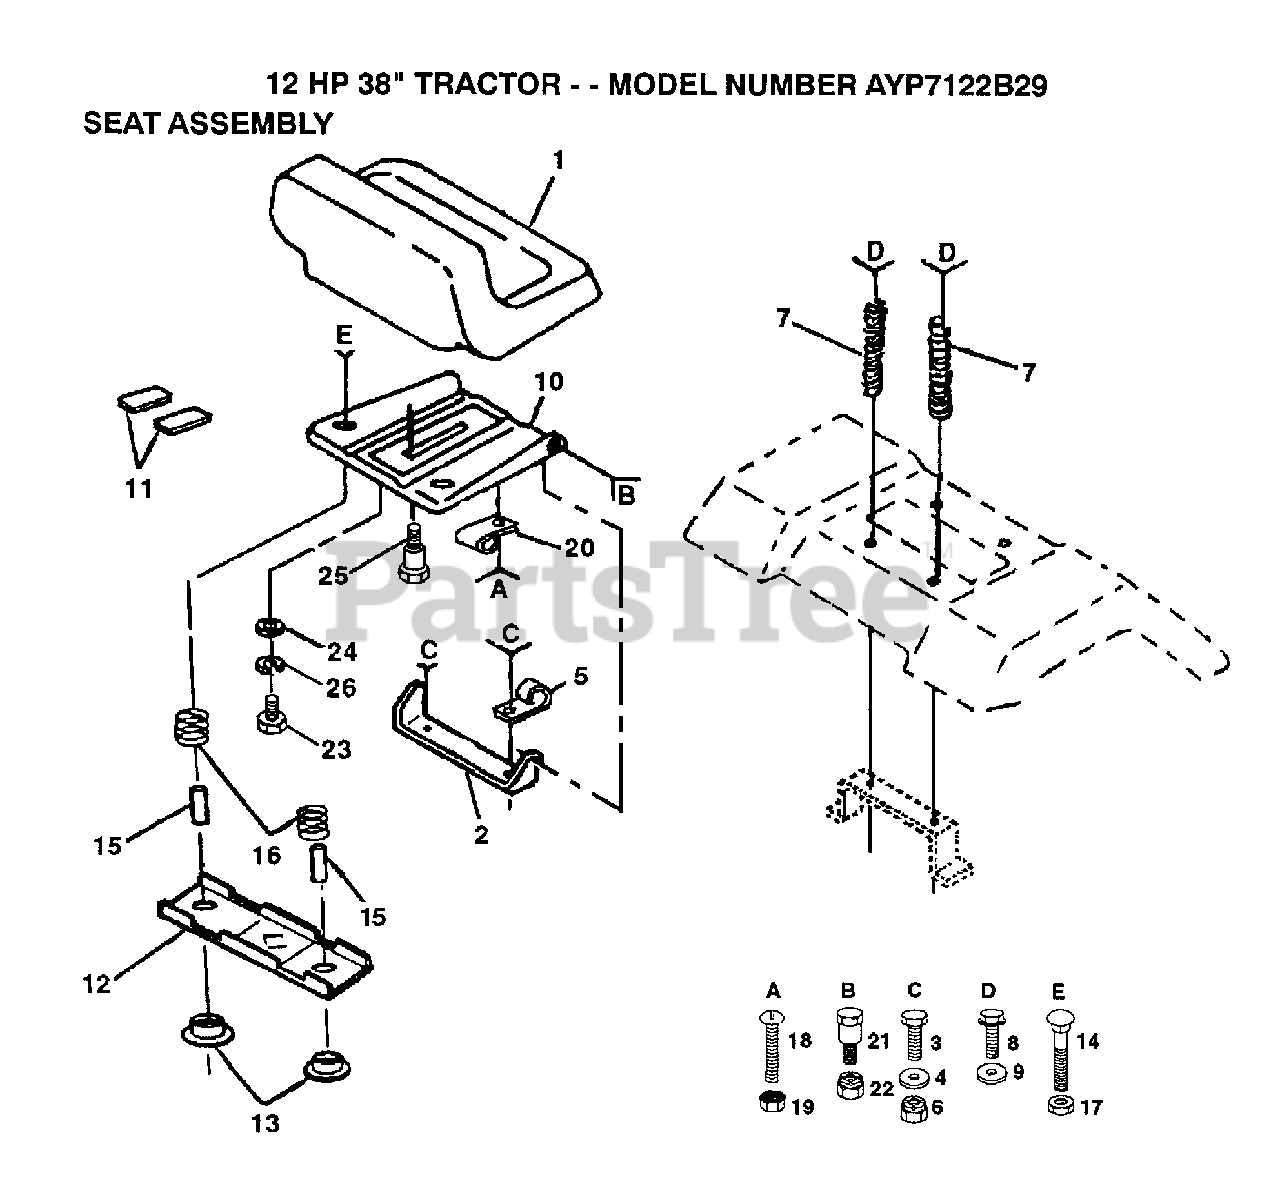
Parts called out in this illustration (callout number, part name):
4	WASHER
5	CLIP T
7	SPRING COMPRESSIO
8	SCREW GTV
9	WASHER
11	STRIP FORM
12	BRKT SWITCH
13	BUSHING
15	SPACER SPLIT
16	SPRING
19	"NUT,KEPS"
23	BOLT
24	WASHER
25	"BOLT,SHOULDER"
26	LOCKWASHER
